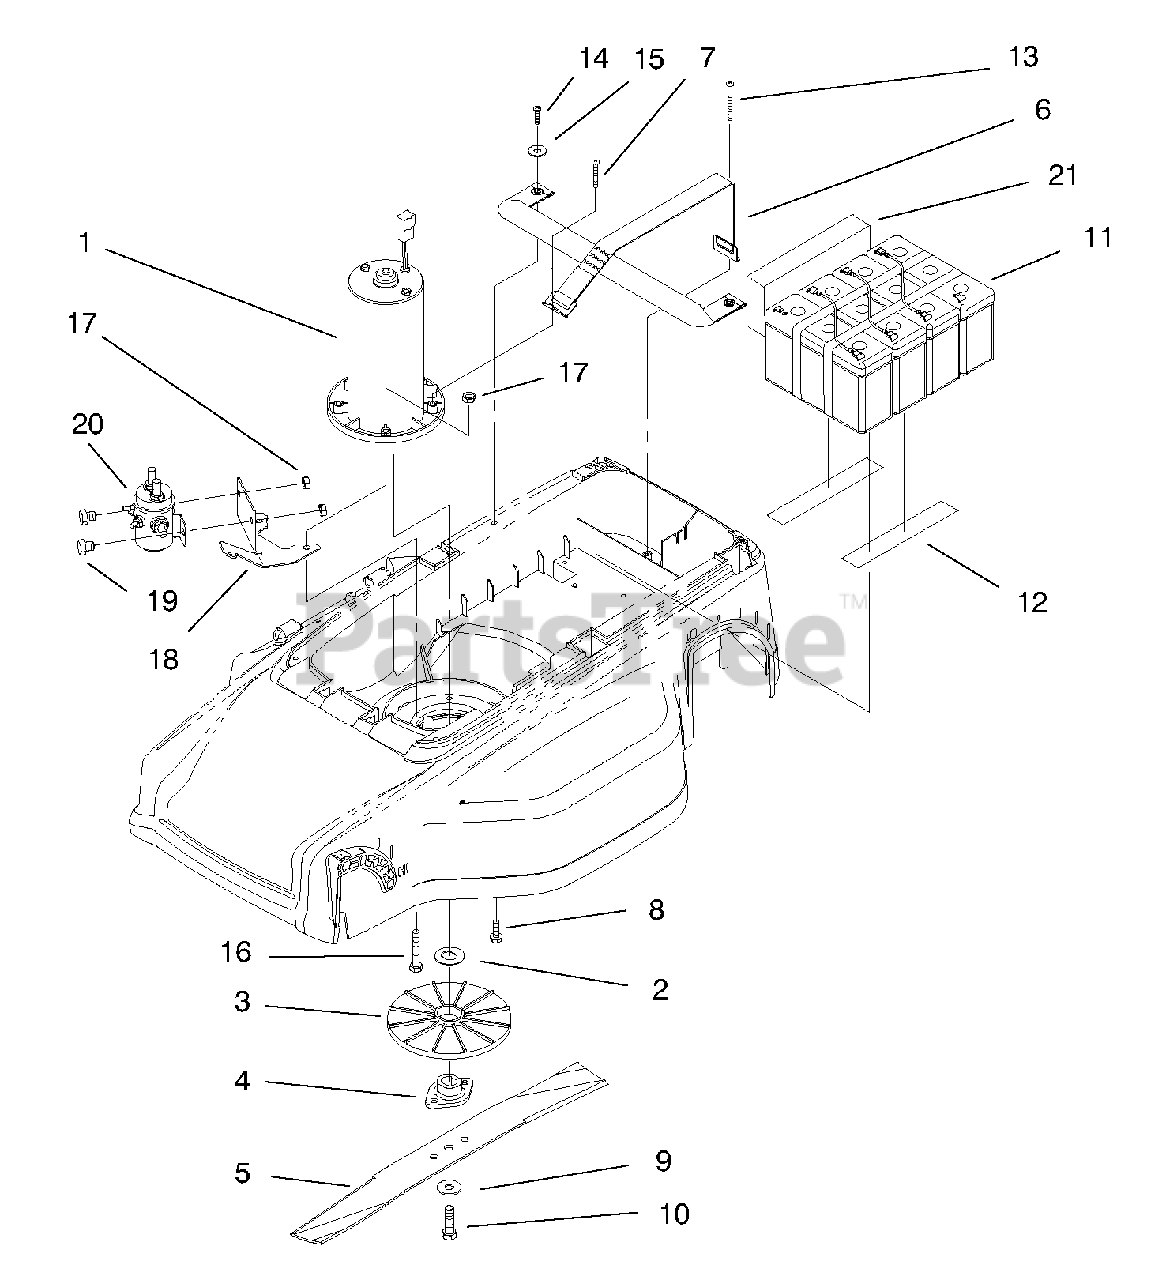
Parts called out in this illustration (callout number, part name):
1	ASM-Motor 24 Volt
5	Blade
6	ASM-Battery Strap
7	Screw-PPH
8	Screw-HWHTF
9	Washer-Spring
10	Bolt-Blade
11	ASM-Battery (Incl. Ref #12)
12	Tape-Foam
13	Screw-PPH
15	Washer-Flat
16	Screw-HWHTF
17	Nut-Lock
18	Bracket-Solenoid
19	Screw-HHF
20	Solenoid-24 Volt
21	Spacer-Foam
